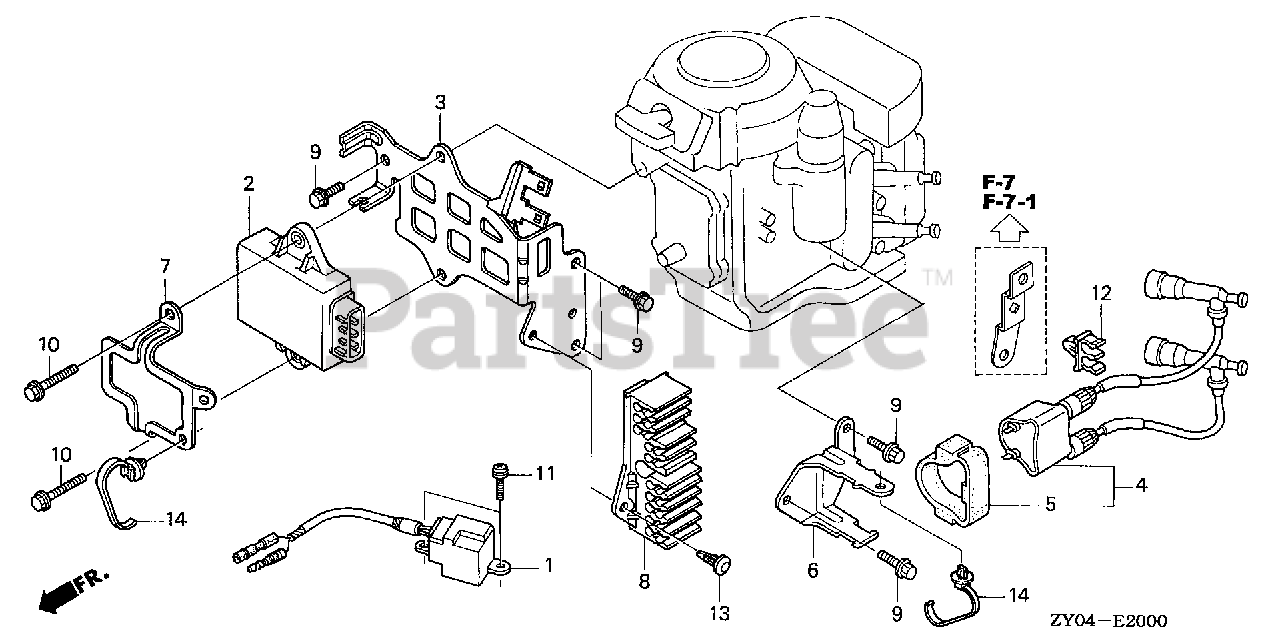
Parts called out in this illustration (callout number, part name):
1	COIL ASSY., PULSER
2	MODULE, IGNITION CONTROL (CDI)
3	PLATE, C.D.I.
4	COIL ASSY., IGNITION
5	SUSPENSION, IGNITION COIL
6	BRACKET, IGNITION COIL
7	BRACKET, C.D.I.
8	BRACKET, CONNECTOR
9	BOLT, FLANGE (6X14) (CT200)
10	BOLT, FLANGE (6X25)
11	SCREW-WASHER (5X16)
12	CLIP, FUEL TUBE
13	CLIP, ANCHOR
14	CLIP, HARNESS BAND (151.5MM) (NATURAL)
